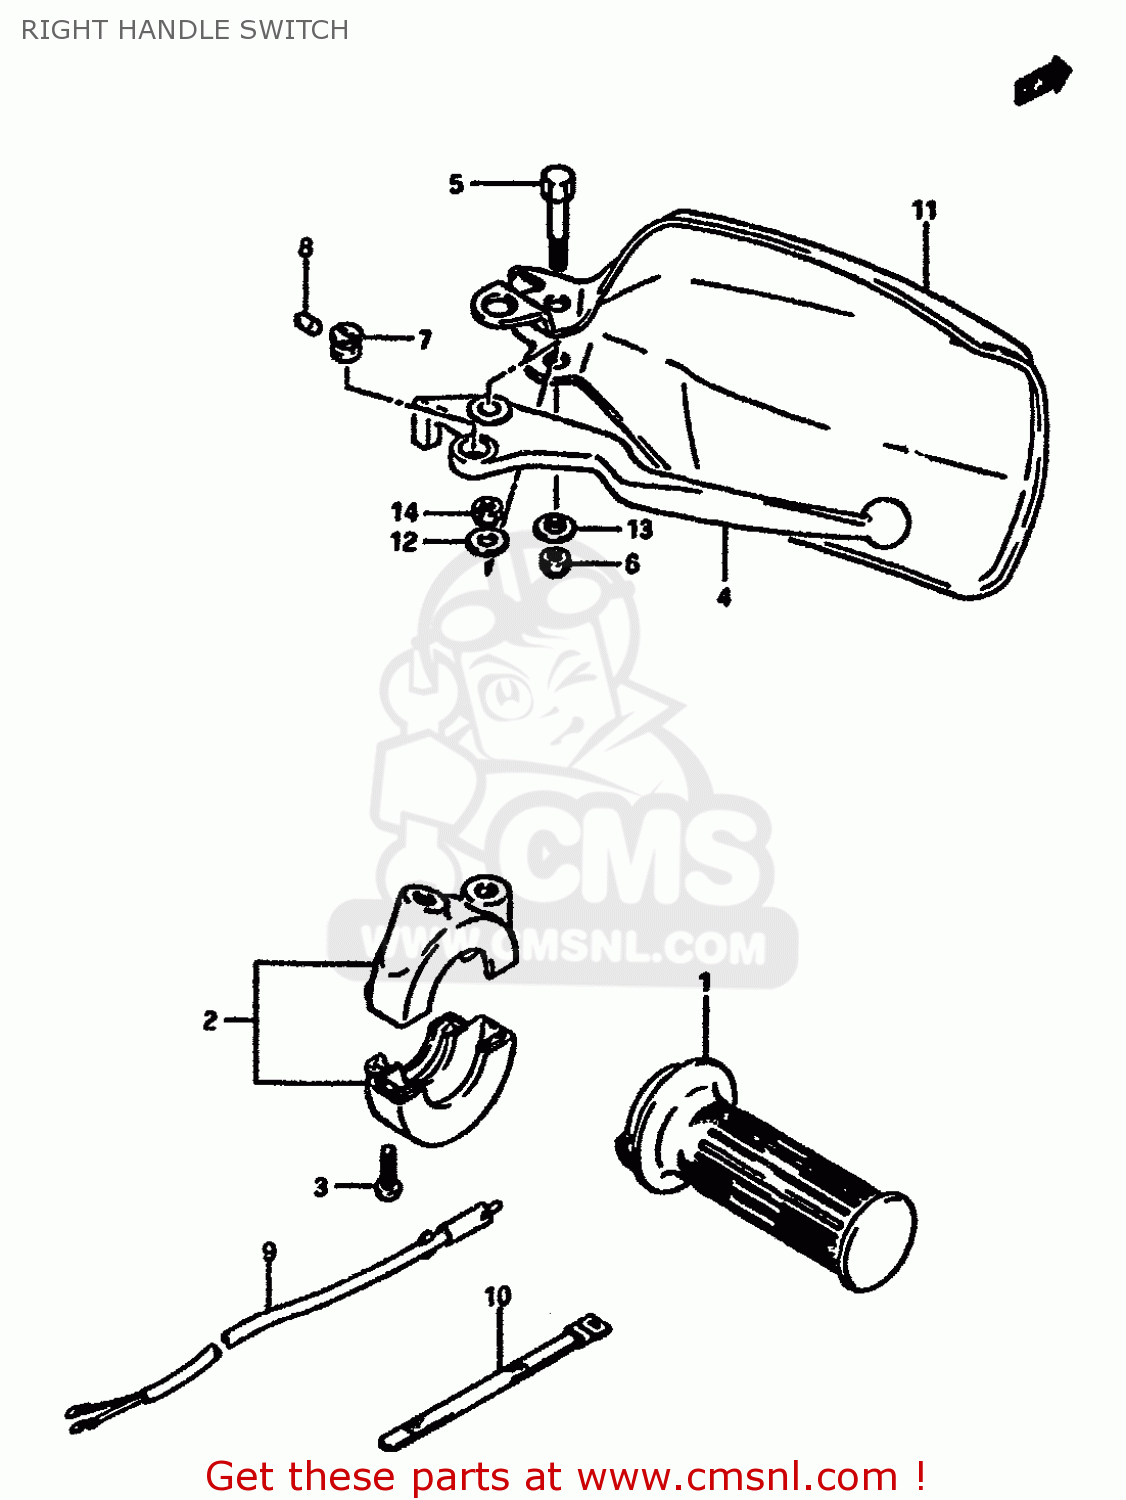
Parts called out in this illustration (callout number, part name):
1	GRIP,THROTTLE
2	CASE ASSY,THROTTLE
3	SCREW 5X20
4	LEVER,BRAKE
5	BOLT,LEVER PIVOT
6	NUT
7	ADJUSTER
8	ROD,PUSH
9	SWITCH ASSY,STOP
10	CLAMP(L:120)
11	COVER,KNUCKLE,R
12	WASHER(6.5X16X1.2)
13	WASHER
14	NUT 6MM
